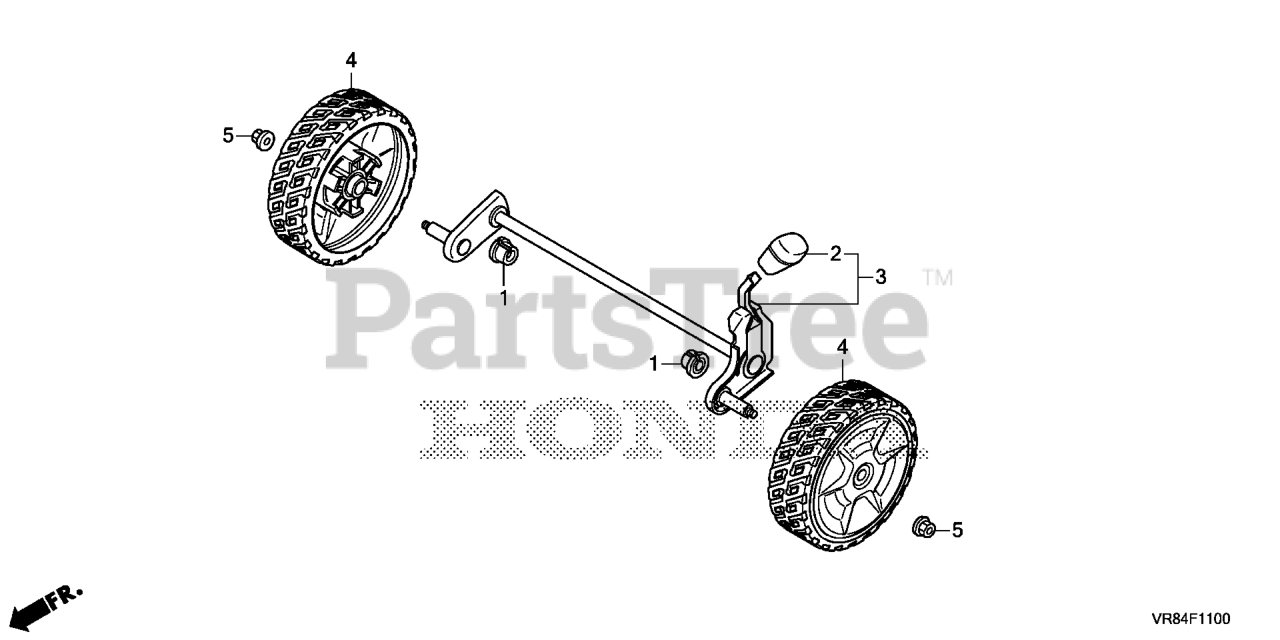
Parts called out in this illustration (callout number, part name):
1	BUSH, FR. AXLE SHAFT
2	GRIP, ADJUSTER *NH164* (GRIP GRAY)
3	SHAFT, FR. AXLE *NH164* (GRIP GRAY)
4	WHEEL, FR. *NH105* (MAT BLACK)
5	NUT, FLANGE (8MM)
